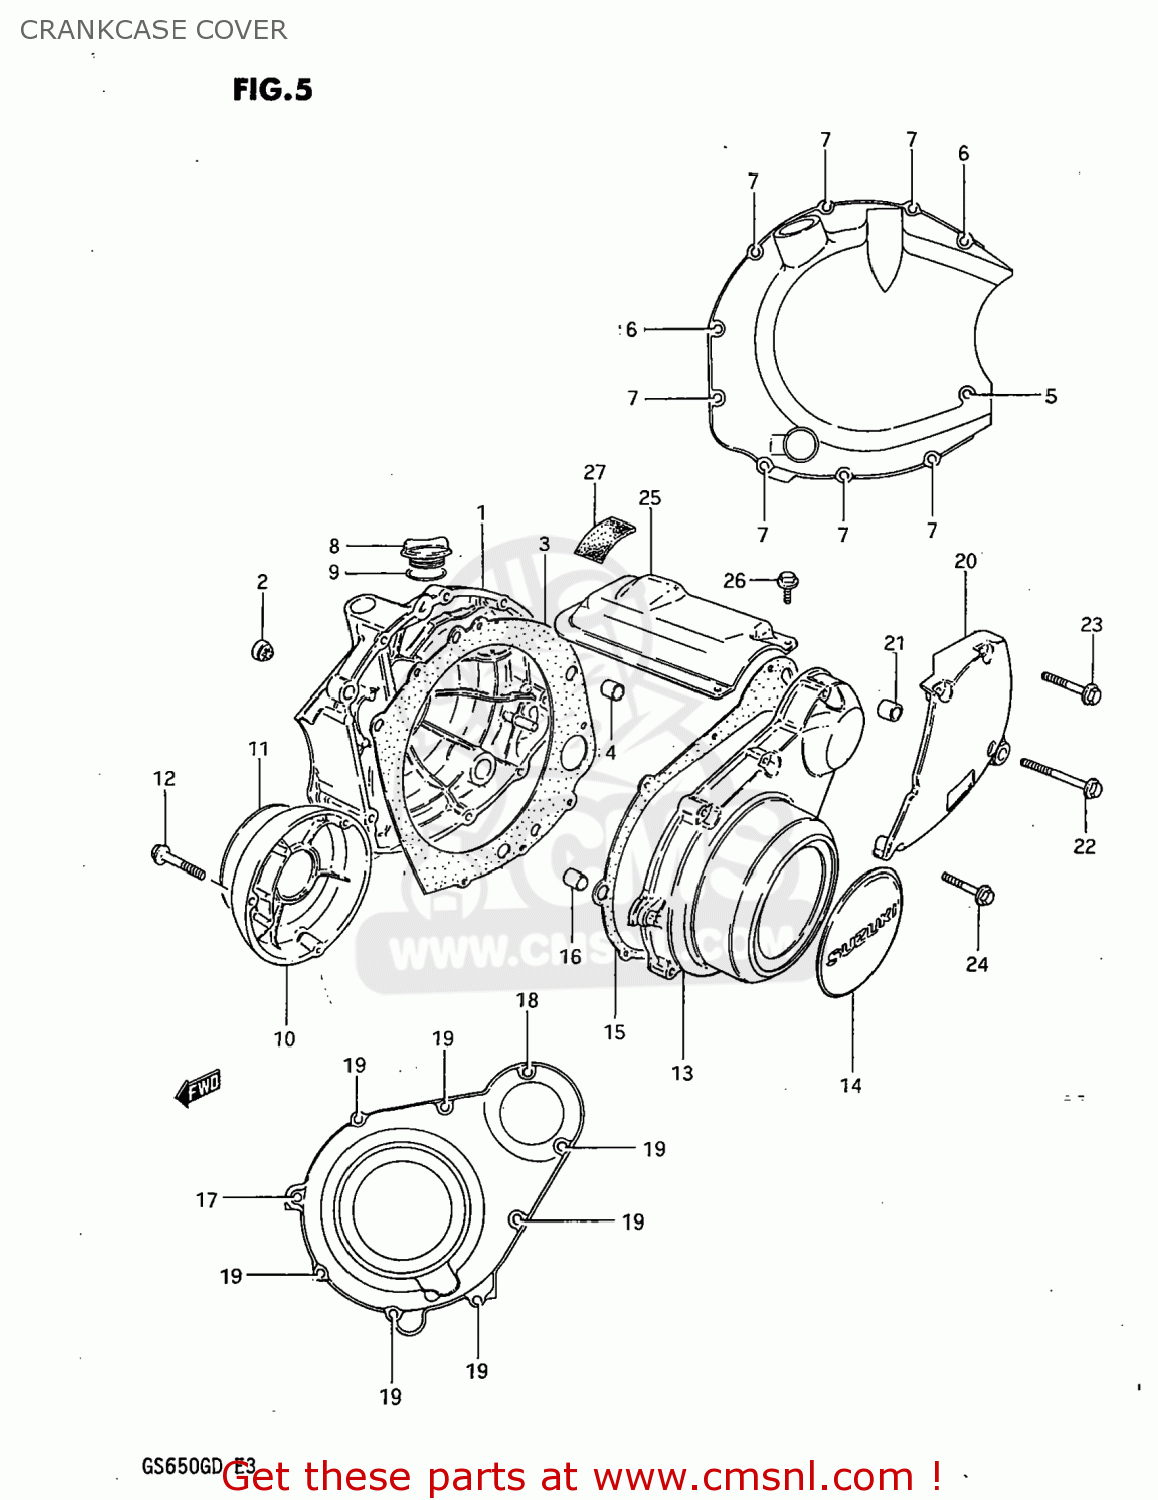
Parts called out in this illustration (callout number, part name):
1	COVER,CLUTCH
2	LENS,OIL LEVEL CHECK
3	GASKET,CLUTCH COVER (MCA)
4	PIN
5	BOLT (6X65)
6	BOLT (6X40)
7	BOLT (6X30)
8	PLUG
9	O-RING
10	COVER,CONTACT BREAKER
11	EMBLEM
12	BOLT (5X30)
13	COVER,MAGNETO
14	EMBLEM,MAGNETO COVER
15	GASKET,MAGNETO COVER (MCA)
16	PIN
17	BOLT
18	BOLT (6X35)
19	BOLT (6X30)
20	COVER,SECONDARY DRIVE
21	PIN
22	BOLT (6X40)
23	BOLT (6X30)
24	BOLT
25	COVER,STARTER MOTOR
26	BOLT
27	DAMPER,STARTER MOTOR CLUTCH
